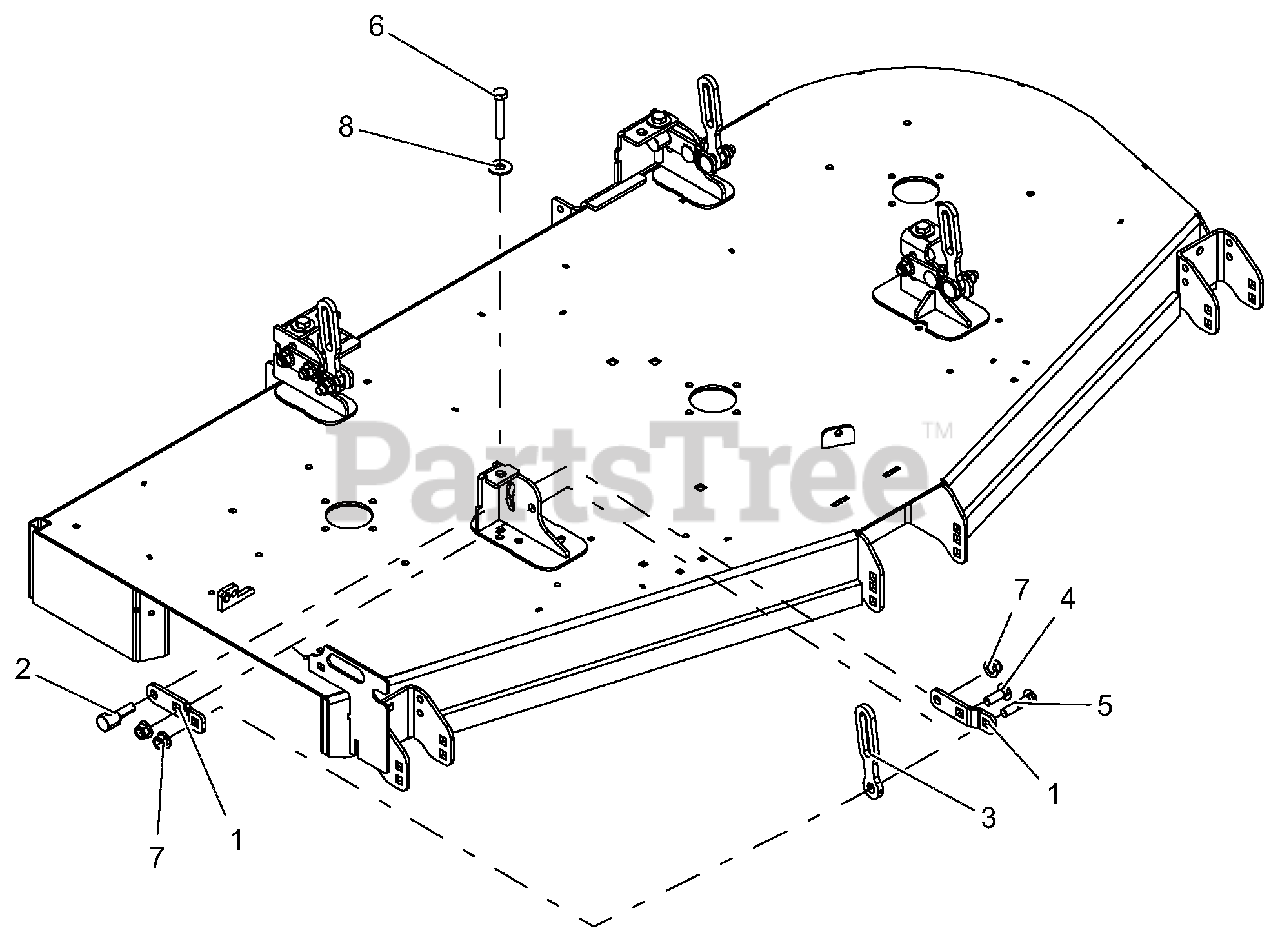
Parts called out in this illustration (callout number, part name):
1	BRKT, DECK LEVELING-BLACK
2	TRUNNION, .50-13
3	LINK, DECK LIFT
4	@BLT-RDHDSQNK .50-13X1.50 G5 YWZC
5	BLT-RDHDSQNK .50-13X2.25 G5
6	BLT-HEX .50-13X3.00 GR5 FTH YWZC
7	NUT-LK-NYL-FLG .50-13 YWZC
8	@WSHR-FL-STL.563X1.38X.109YWZC
